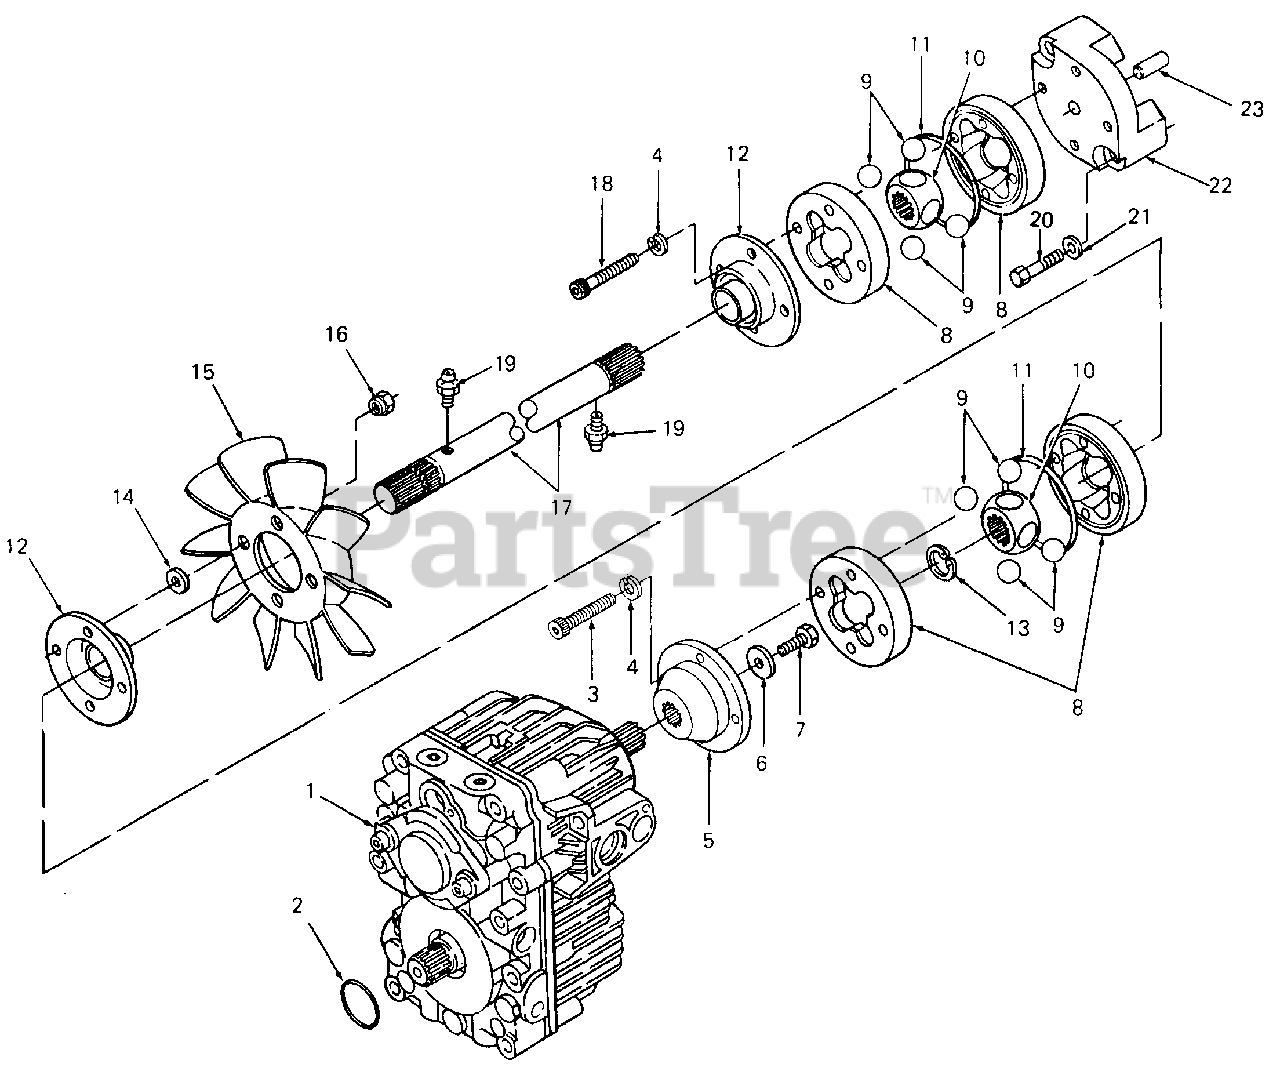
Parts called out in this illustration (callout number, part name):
1	Pump, Hydrostatic
2	O-Ring, 2.75 ID X .103 Dia
3	Screw, Socket Hd Cap, 1/4-20 X 2.0 Lg
4	Washer, Lock, 1/4
5	Adapter, Pump
6	Washer, Bell, .265 X .75 X .062 Thk
7	Bolt, Hex Patch, M6-1.0 X 20 MM Lg GR10.9
8	Coupling, Drive w/O-Ring Groove
9	Ball, Steel, 5/8 Dia Chrome
10	Hub, Drive
11	O-Ring, 2.489 X .070
12	Boot, Coupling
13	Ring, Snap
14	Washer, Flat, .25 X .62 X .052 Thk
15	Fan, 10 Blade Hydro
16	Nut, Fan, 1/4-20
17	Shaft, Drive, 21.3 Lg
18	Screw, Socket Hd Cap, 1/4-20 X 1.75 Lg
19	Fitting, Grease
20	Screw, Hex Cap, 5/16-18 X 1.75 Lg GR5
21	Washer, Flat, .312 X .750 X .119 Thk
22	Adapter, Drive Shaft
23	Pin, Locating
